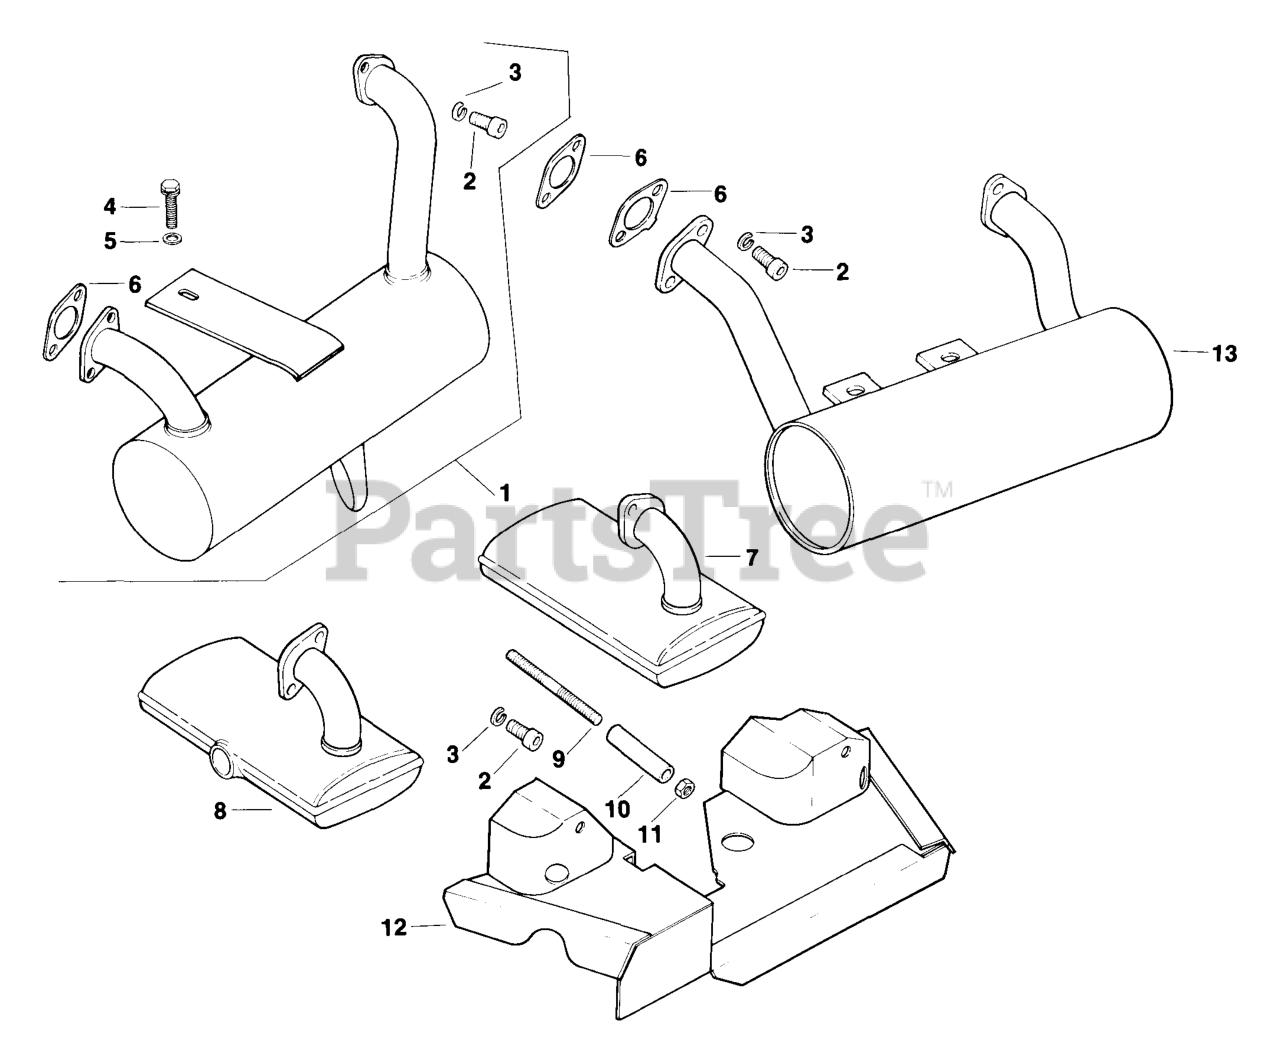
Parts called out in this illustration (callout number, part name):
2	Screw, Hex. Socket Hd. Cap 5/16-18x3/4
3	Washer, Lock 5/16"
4	Screw, H.C. Sems 1/4-20x5/8"
6	Gasket, Exhaust
